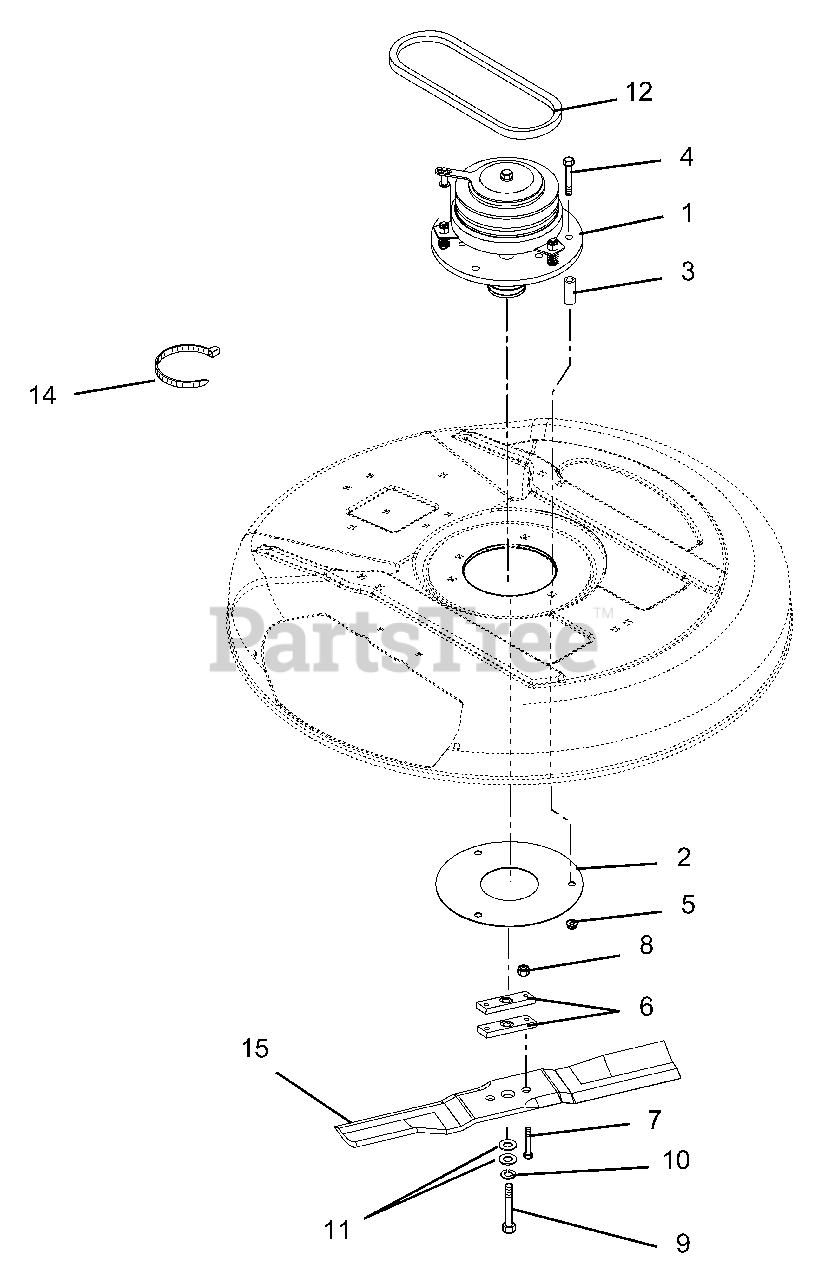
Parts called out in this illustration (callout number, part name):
1	KIT, CLUTCH (1232 RER)
2	SHEILD, CLUTCH
3	SPACER .380 X .625 X 1.500
4	@BLT-HEX .38-16X2.75 GR5 YWZC
5	@NUT-LK-TOP-FLG .38-16 YWZC
6	SPACER, 28/32 BLADE
7	BLT-HEX .38-24 X 2.00 GR8 YWZC
8	NUT-LK-NYL .375-24 W/INSR YWZC
9	BLT-HEX .62-18X2.5 GR8 YZ
10	@WSHR-LK .62X.156 REG YWZC
11	@WSHR-FL-STL.656X1.31X.095 YWZ
12	V-BELT, HA-RAW EDGE
12	BELT,HA WRAPPED
13	J-CLAMP
14	CABLE TIE LG 5-1/2
15	BLADE-CUTTING 28"
15	BLADE, 32" RER/ZS
